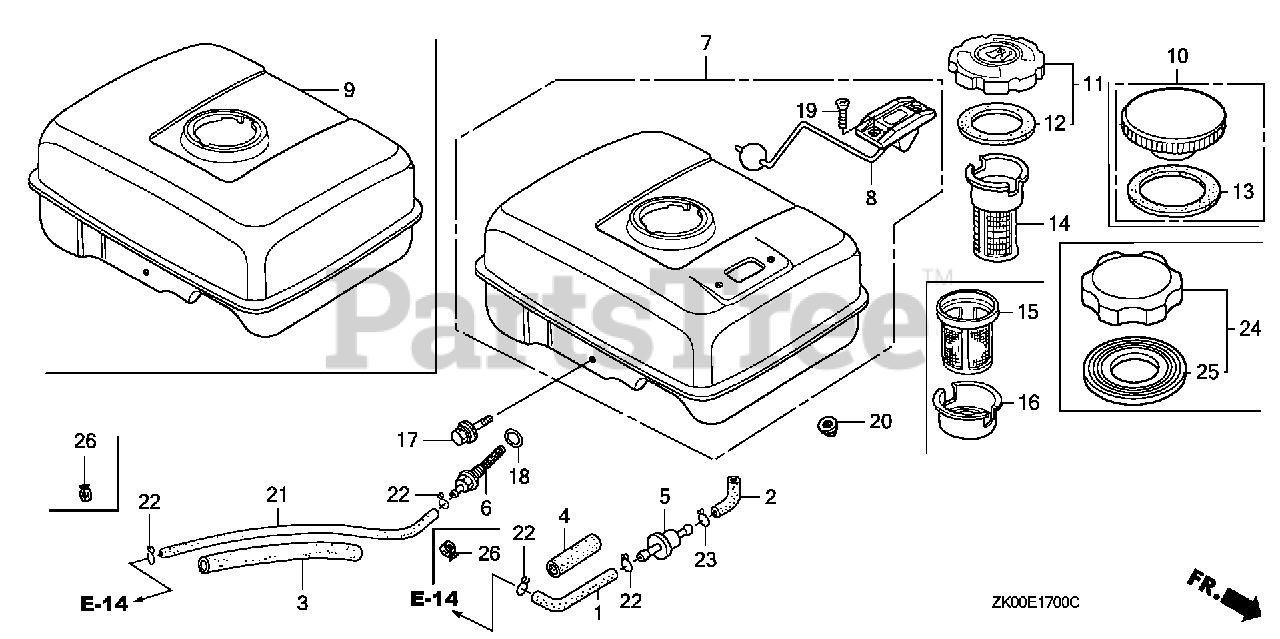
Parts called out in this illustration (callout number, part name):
3	RUBBER, SUPPORTER (107MM)
6	JOINT, FUEL TANK
9	TANK, FUEL *NH31* (MCKINLEY WHITE)
17	BOLT, FLANGE (6X34)
18	O-RING (13.5X1.5) (ARAI)
18	O-RING (14MM) (NOK)
20	NUT, FLANGE (6MM)
21	BULK HOSE, FUEL (4.5X3000) (4.5X140)
22	CLIP, TUBE (B8)
24	CAP, FUEL FILLER (CHROME PLATED)
25	GASKET, FUEL FILLER CAP (39X62X3) (TOUYOUSYA)
